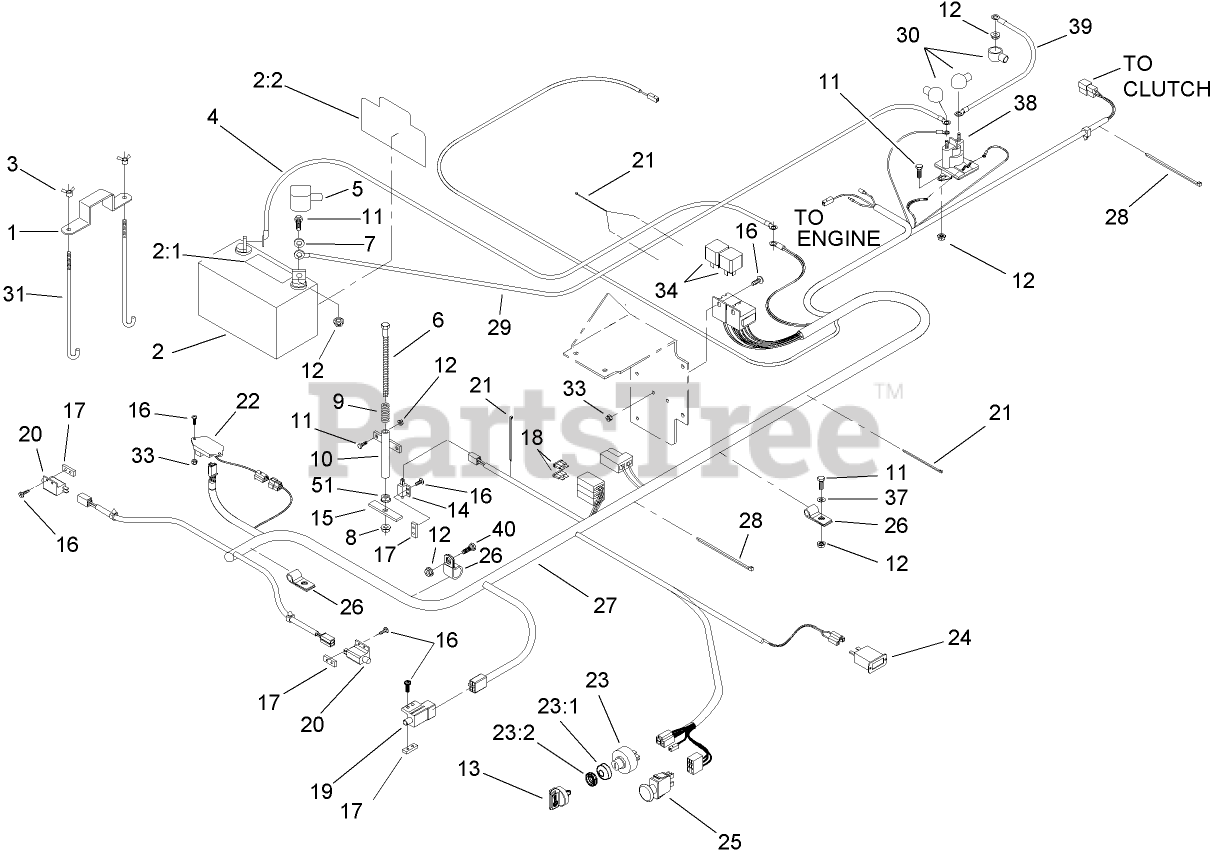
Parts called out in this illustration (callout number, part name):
1	STRAP-HOLDDOWN
2	BATTERY
2:1	Decal-Battery
2:2	Decal-Battery
3	WINGNUT
4	WIRE-GROUND
5	INSULATOR-BATTERY
6	SCREW-HH
7	WASHER-FLAT
8	NUT-LOCK, NI
9	SPRING-SWITCH, SEAT
10	MOUNT-SPRING, SEAT
11	SCREW-HH
12	NUT-HF
13	KEY-IGNITION
14	SWITCH-CLOSED, NORMALLY
15	PLATE-SWITCH, SEAT
16	SCREW-PPH
17	PLATE-TAPPED
18	FUSE-BLADE TYPE, 20 AMP
19	SWITCH
20	SWITCH-OPEN, NORMALLY
21	TIE-CABLE
22	MODULE-DELAY, SEAT
23	Key Switch ASM
23:1	WASHER-TOOTH, INTERNAL
23:2	NUT-HH
24	METER-HOUR
25	SWITCH-DELTA
26	CLIP-LOOM
27	Harness-Wire
28	TIE-PLASTIC
29	WIRE-STARTER
30	INSULATOR-SOLENOID
31	BOLT-HOLDDOWN
33	NUT-LOCK, NI
37	WASHER-FLAT
38	SWITCH-SOLENOID
39	CABLE-STARTER, POSITIVE
40	SCREW-HH
51	NUT-HEX
